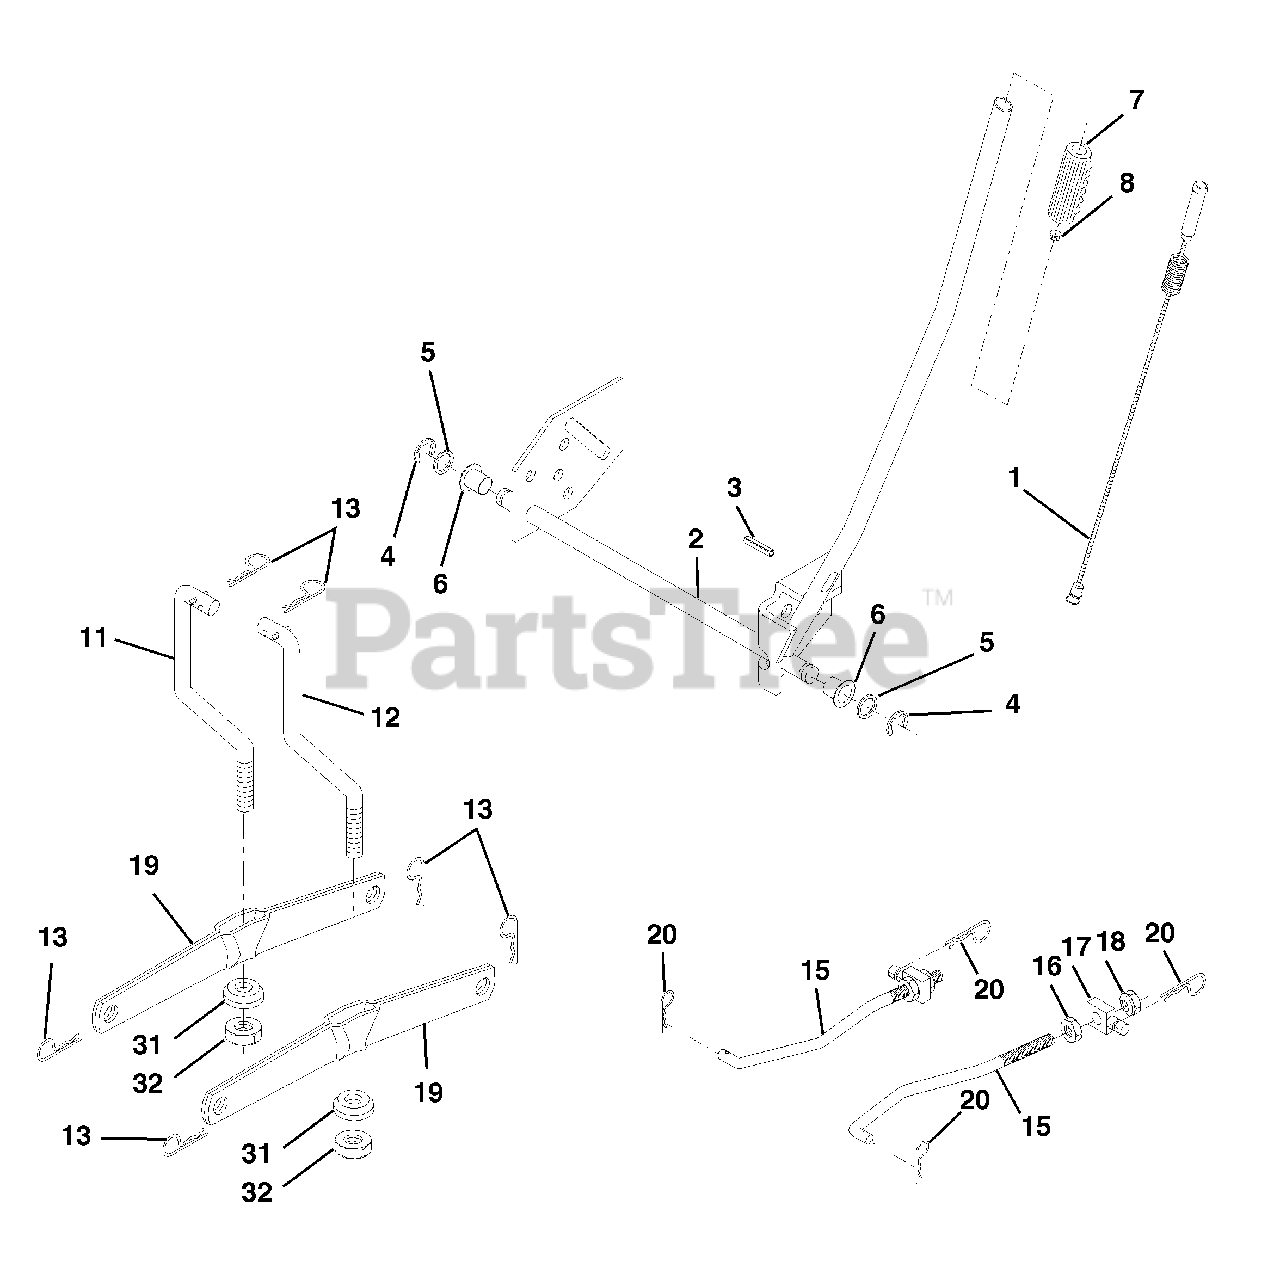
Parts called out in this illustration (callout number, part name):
1	Wire Asm Inner W/plunger LT
2	Shaft Asm Lift
3	Pin Groove
4	E Ring #5133-62
5	Washer PLTD 21/32 X 1 X 21ga
6	Bearing Nylon Blk 629 Id
7	Grip Handle Bicycle
8	Button Plunger Black
11	Link Lift LH
12	Link Lift RH
13	Retainer Spring
15	Link Front
16	Nut Jam Hex 1/2-13 Unc
17	Trunnion Blk Zinc
18	Nut Crownlock 1/2-13 Unc
19	Arm Suspension Rear
20	Spring, Retainer
31	Bearing Pvt. Lift Spherical
32	Nut Crownlock 3/8-24
